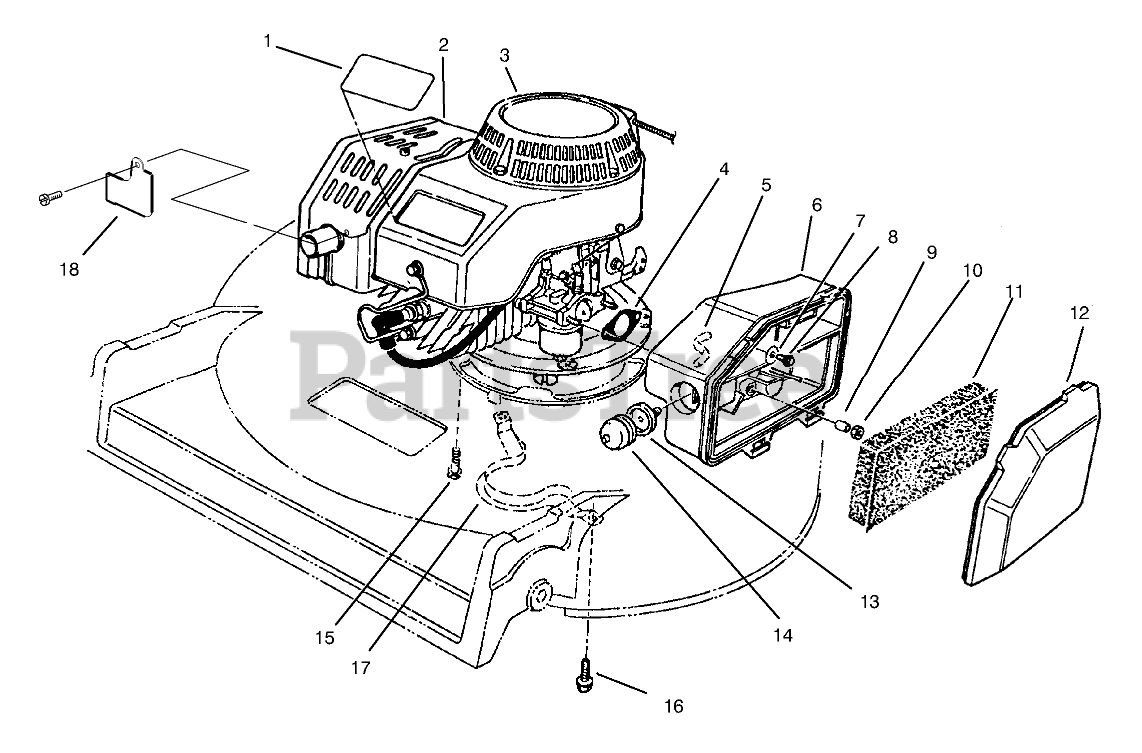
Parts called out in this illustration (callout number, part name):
1	DECAL - PROLINE
2	ENGINE ASM - BBC 2 CYCLE
3	DECAL-2 CYC RECOIL COMM
4	GASKET-AIR CLEANER
5	HOSE-PRIMER
6	BODY-AIR CLEANER
7	WASHER-FLAT
8	SCREW-HH
9	SPACER
11	ELEMENT-AIR CLEANER
12	COVER-AIR CLEANER
13	BODY-PRIMER
14	BULB-PRIMER
15	SCREW-HHF
16	SCREW-HWHTF
17	Guide-Belt
18	EXTENSION-MUFFLER GUARD
